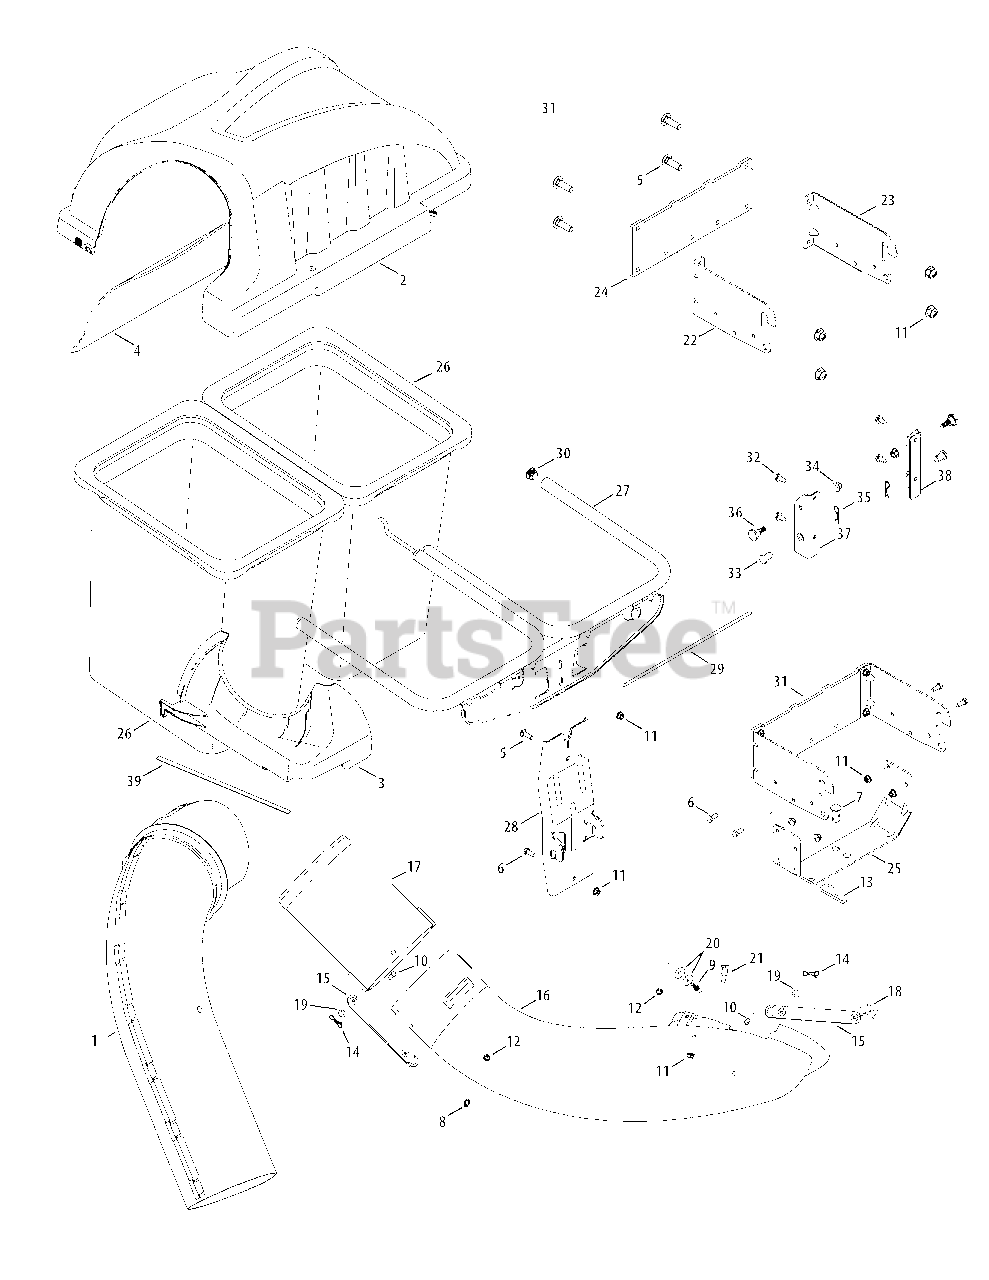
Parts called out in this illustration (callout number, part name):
1	Upper Chute Assembly
2	Double Bagger Cover Assembly
3	Upper Chute Support
4	Bagger Cover Screen
5	Carriage Screw, 5/16-18 x 1.00"
6	Hex Head Screw, 5/16-18 x .75"
7	Clevis Pin, .62" Dia.
8	Grass-catcher Pin, 1/4-20
9	Attachment Pin, 1/4 x 0.66 Lg.
10	Clevis Pin, 5/16 x .75 Lg.
11	Flange Lock Nut, 5/16-18
12	Flange Lock Nut, 1/4-20
13	Internal Cotter Pin, .148 x 3.00
14	Bow-Tie Cotter Pin, 72
15	Chute Strap, 6.00 Lg.
16	Bagger Discharge Chute, Elbow
17	Bagger Chute Adapter, 7 In.
18	Torsion Spring Hook
19	Flat Washer, .344 x .62 x .033
20	Flat Washer, .265 x .938 x .120
21	Shoulder Screw, .437 x .54
22	Mounting Bracket, RH
23	Mounting Bracket, LH
24	Universal Mounting Bracket
25	Universal Support Bracket
26	Grass-bag Assembly
27	Double Bag Support Assembly
28	Vertical Support Bracket
29	Cover Hinge Pin
30	End Plug
31	Mounting Bracket Kit (Incl. ref. 22, 23, 24)
32	Tap Screw, 5/16-18 x .750
33	Clevis Pin, .50 x .78
34	Flange Lock Nut, 3/8-16
35	Click Pin, .092 x 1.64 Lg.
36	Shoulder Screw, .625 x .412
37	Mounting Bracket, RH
38	Mounting Bracket, LH
39	Self-Adhesive Foam Strip
